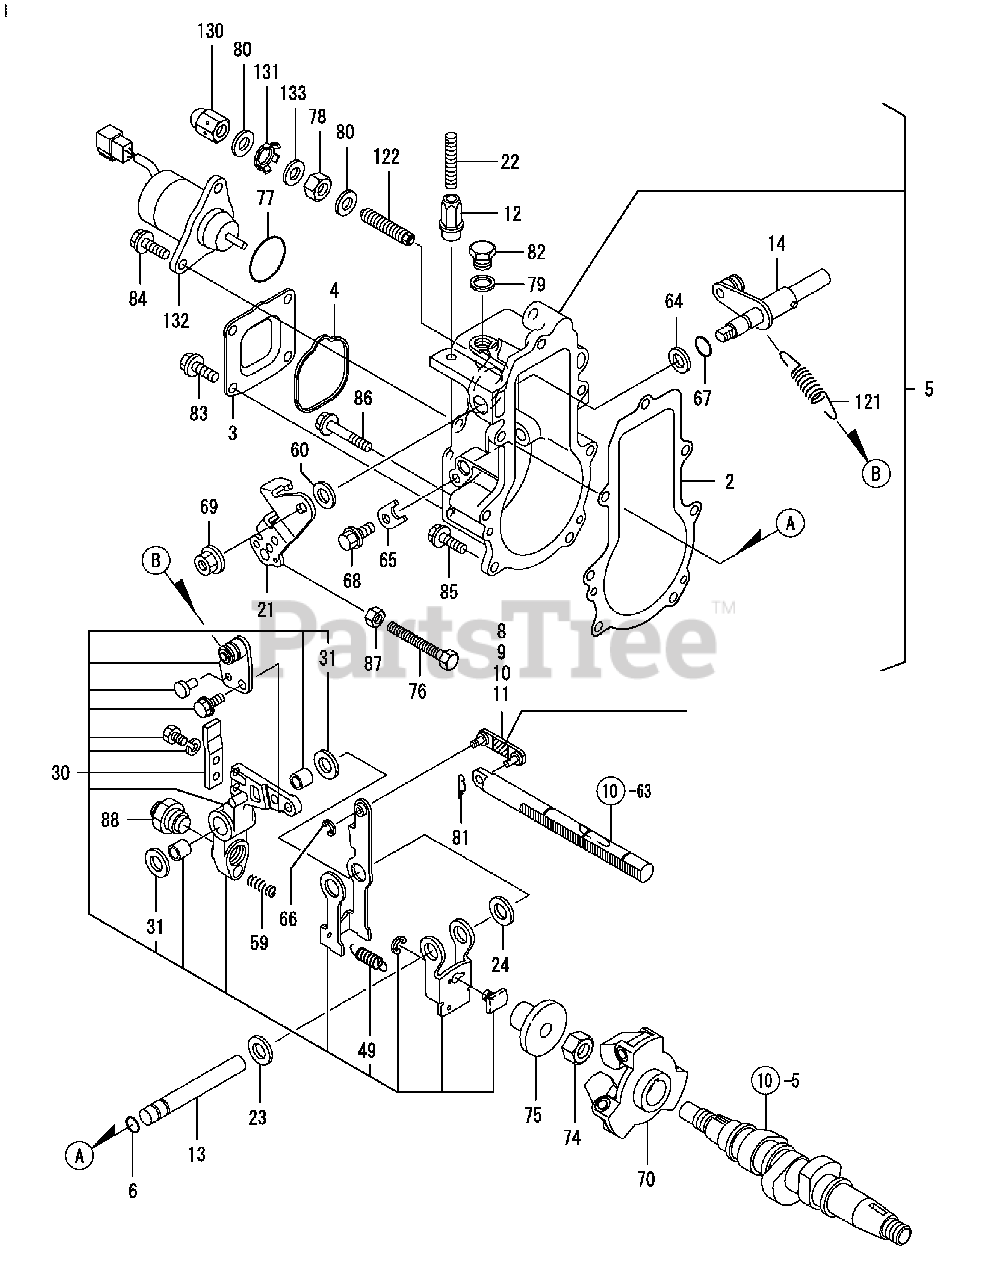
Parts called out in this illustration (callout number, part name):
3	Case, Governor
5	Case Assembly, Governor
13	Shaft, Gov. Lever
14	Shaft Assembly, Control
21	Lever, Control
22	Bolt, Revol. Limit
24	Spacer Assembly
30	Lever Assembly, Governor
59	Spring, Fuel Control
65	Retainer, Shaft
68	Bolt, 6 x 10 Plated
70	Weight Assembly
74	Nut, Governor Weight
76	Bolt, Idle Limit
83	Bolt, 6 x 10 Plated
84	Bolt, M 6 x 14 Plated
85	Bolt, M 6 x 20 Plated
86	Bolt, M 6 x 45 Plated
88	Angleich Assembly
121	Spring, Governor
122	Limiter Assembly, Fuel
132	Solenoid, Stop
